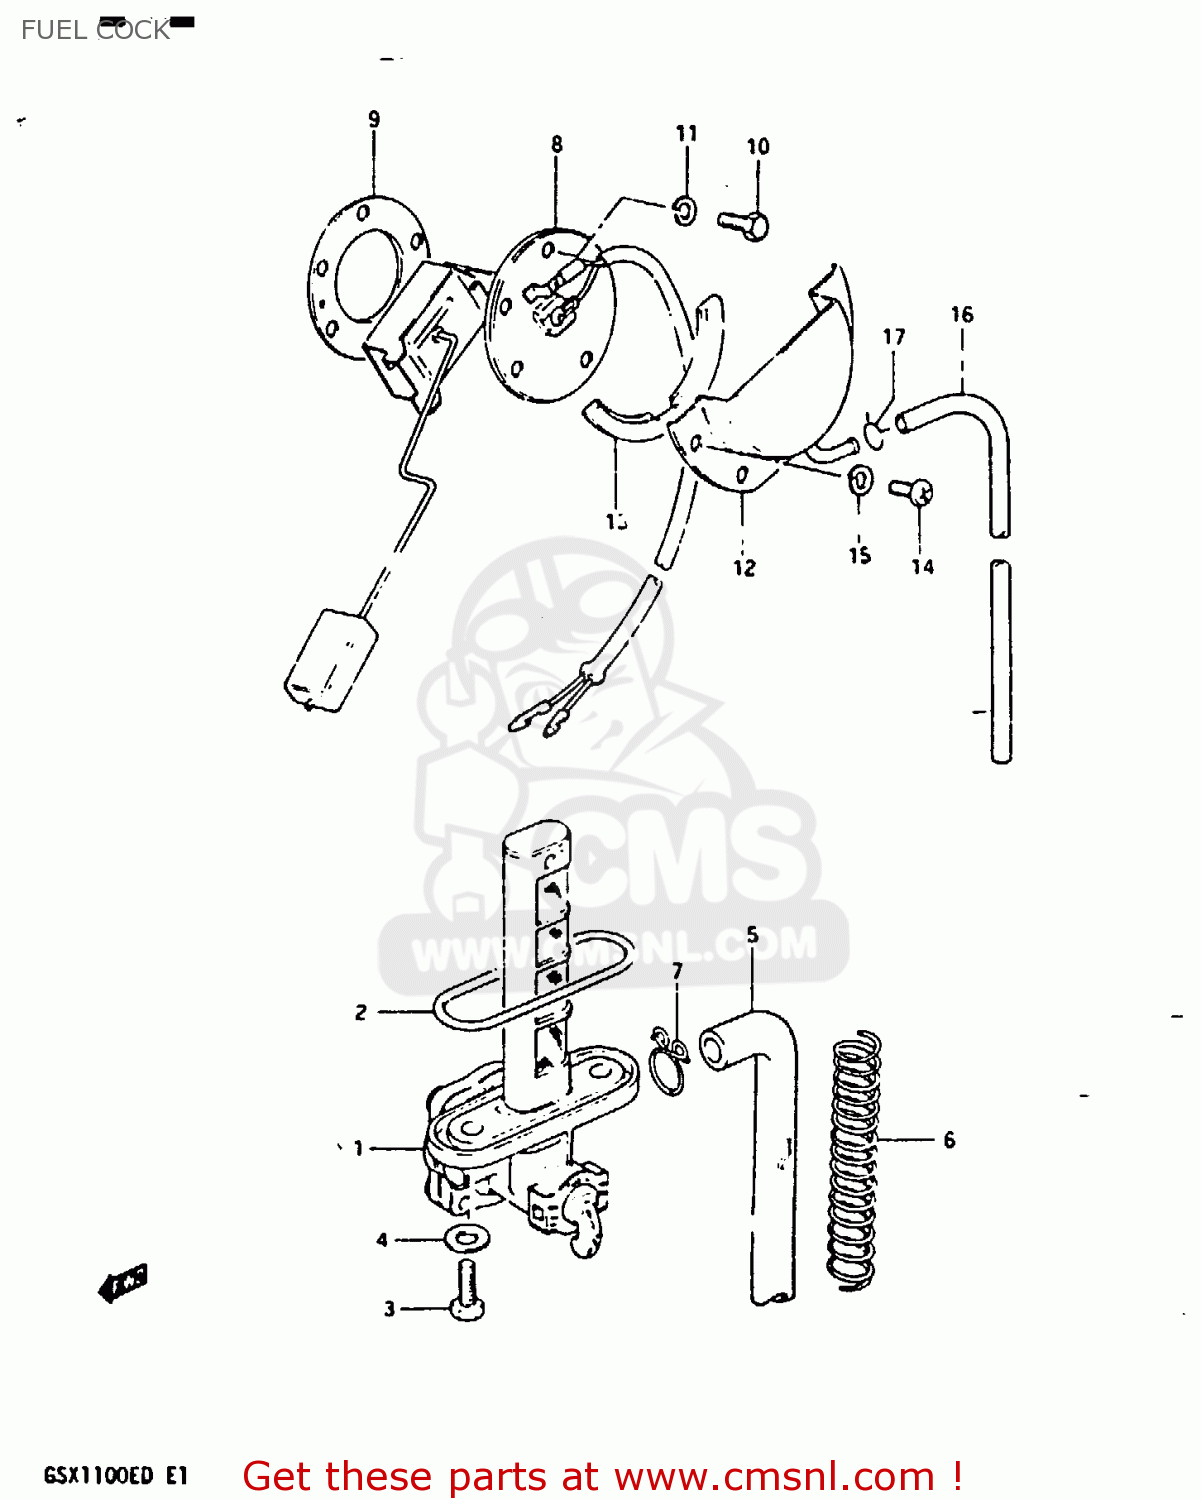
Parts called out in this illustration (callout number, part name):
1	COCK ASSEMBLY,FUEL
2	O RING
3	BOLT(6X20)
4	GASKET
5	HOSE
6	SPRING
7	CLIP
8	GAUGE ASSEMBLY,FUEL LEVEL
9	GASKET,FUEL LEVEL GAUGE (NAS)
10	BOLT
11	LOCK WASHER
12	PLATE,FUEL DRAIN
13	GASKET
14	SCREW
15	LOCK WASHER
16	HOSE,FUEL
17	CLIP
